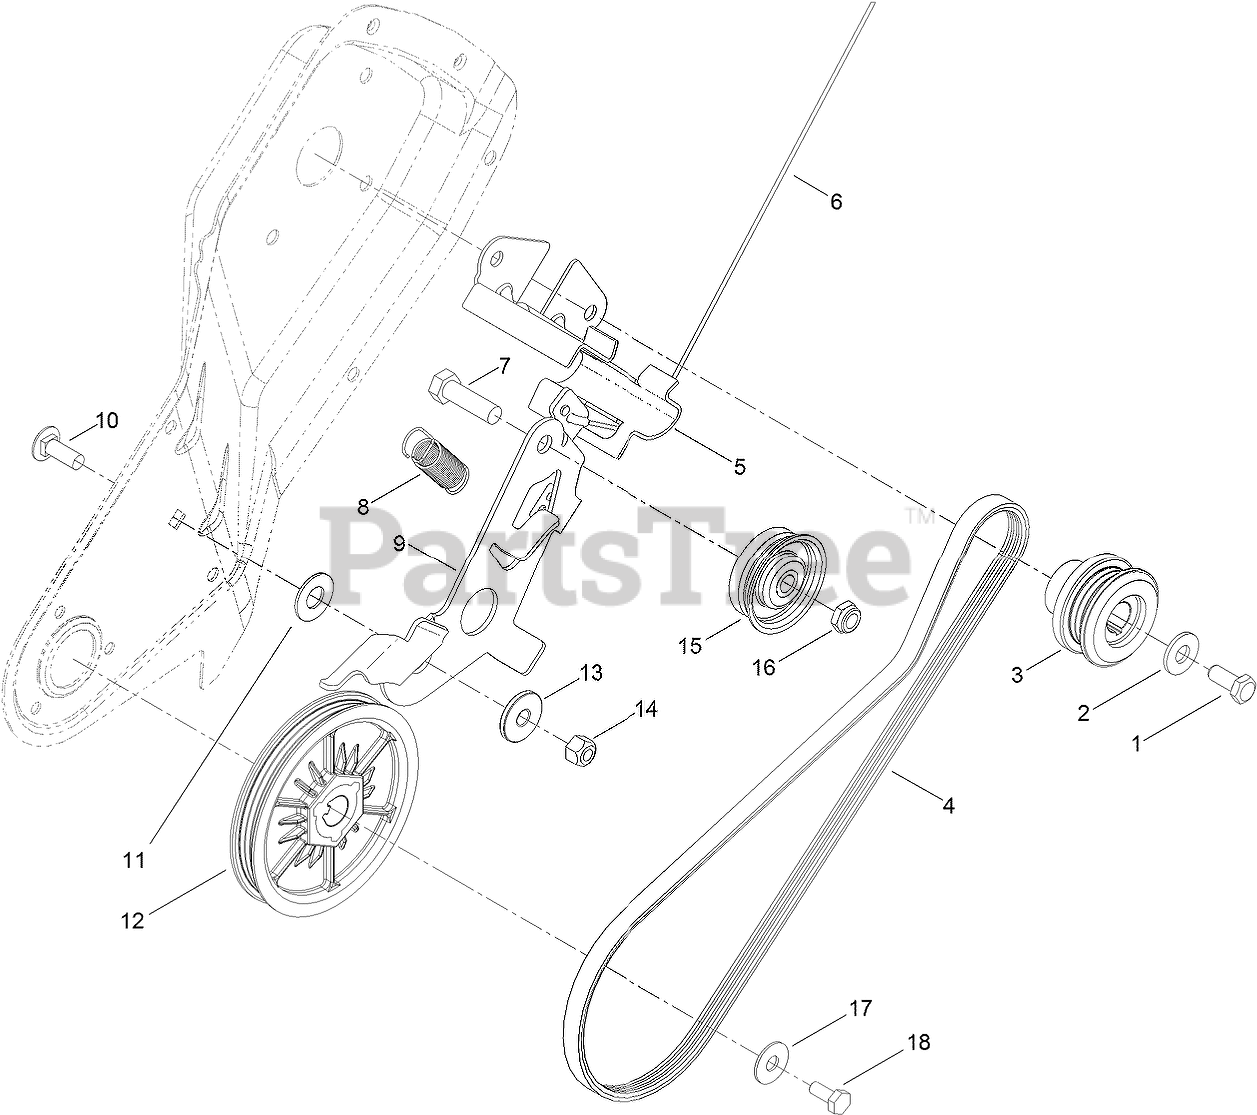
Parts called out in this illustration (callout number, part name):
1	SCREW-HH
2	WASHER-FLAT
3	PULLEY-ENGINE
4	BELT-V, RIBBED
5	GUIDE-BELT
6	CABLE-CLUTCH
7	SCREW-HH
8	SPRING-BRAKE
9	ARM-IDLER
10	BOLT-CARR
11	WASHER
12	ROTOR PULLEY ASM
13	BUSHING-IDLER
14	NUT-LOCK, NI
15	PULLEY-IDLER
16	NUT-LOCK, NI
17	WASHER-BELLEVILLE
18	SCREW-HH
